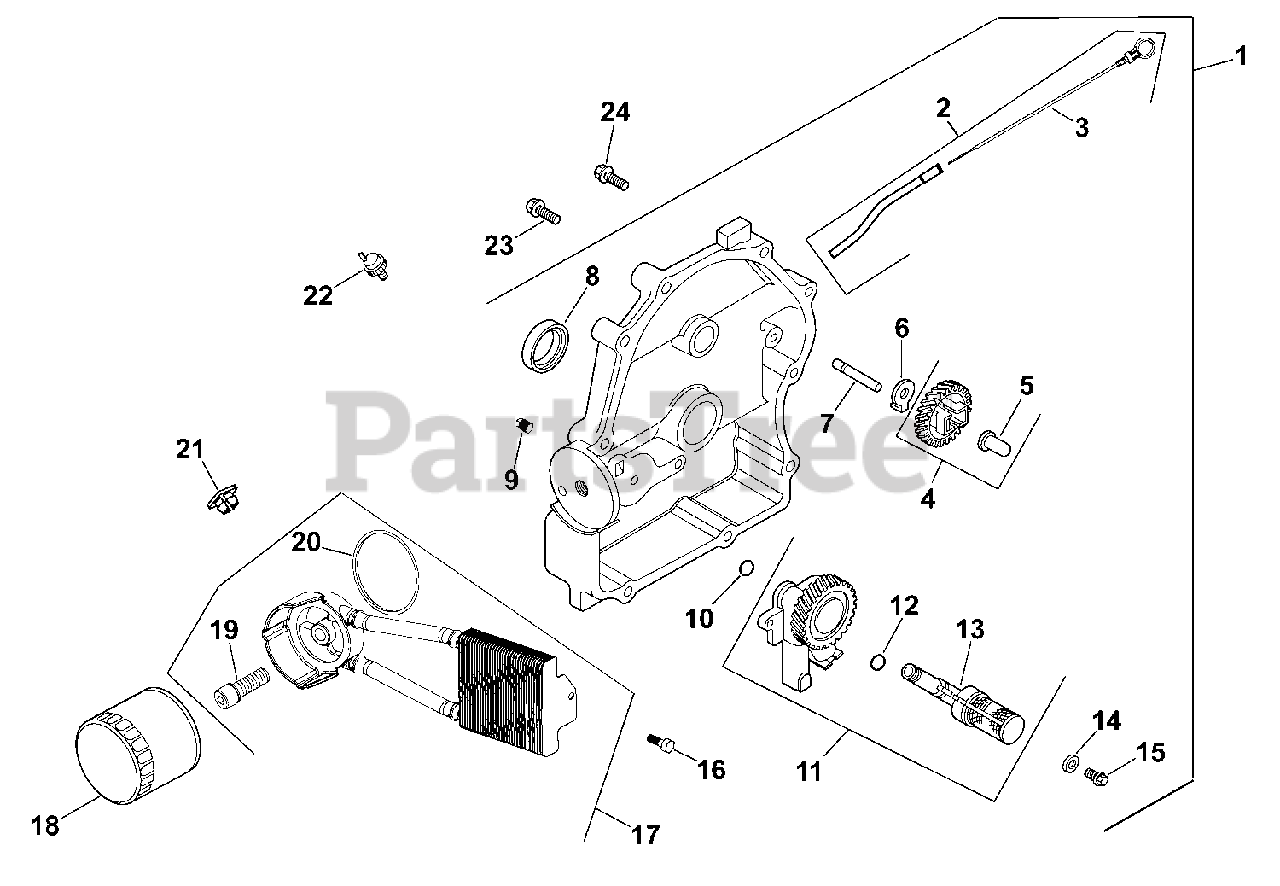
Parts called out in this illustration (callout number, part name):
2	KIT, DIPSTICK/DIPSTICK TUBES
4	KIT, GOVERNOR GEAR W/PIN
5	PIN, GOVERNOR REGULATING
6	TAB, LOCKING
7	SHAFT, GOVERNOR GEAR
8	SEAL, OIL (KM)-USE 25 032 06-S
9	PLUG, CTSK PIPE 1/8"
11	OIL PUMP ASSY KIT-USE 24 393 53-S
12	O-RING, OIL PICK-UP
13	PICK-UP, OIL
14	WASHER, FLAT 6 MM
15	SCREW,FLG THD FRM M6X1.0X25-(#25086395S)
16	SCREW, TAP M6X1.7X18
17	KIT, OIL COOLER
18	OIL FILTER
19	NIPPLE, OIL FILTER
20	O-RING, OIL COOLER
21	NUT, PLASTIC (KM)-USE 25 100 37-S
22	SWITCH, PRESSURE (CLOSED)-USE 25 099 27-
23	SCREW, HEX FLANGE -USE 24 086 17-S
24	SCREW, FLG M8X1.25X45
